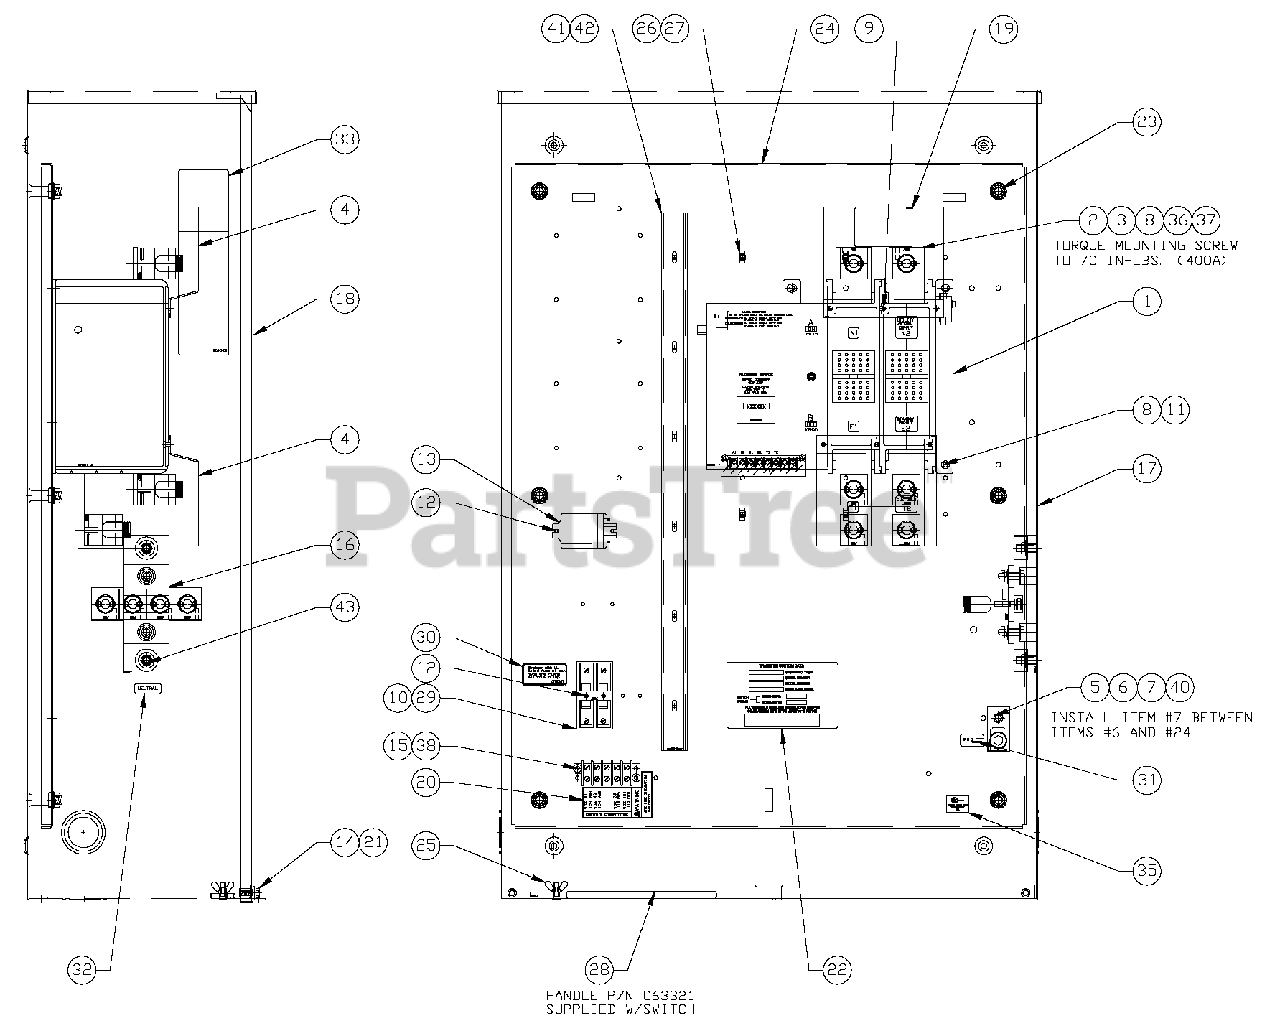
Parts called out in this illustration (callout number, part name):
1	XFER SW-W 400A600V2P
2	LUG SLDLSS 600/250-1/0X1/4-28
3	SCREW HHTT #8-32 X 1/4 CZ
4	COVER LUG 2P 300/400AMP
5	SCREW HHTT 5/16-18 X 3/4 CZ
6	LUG SLDLSS 350-#6 X 13/32 AL/CU
7	WASHER SHAKEPROOF EXT 5/16 STL
8	WASHER LOCK M6-1/4
9	SCREW PPHM DSEMS M4-7 X 10 ZNC
10	FUSEBLOCK 30A 600V 2 POS W/SQ
11	SCREW HHTT M6-1.0 X 12 ZINC
12	SCREW HHTT M4-0.7 X 10 BP
13	RELAY PNL 12VDC DPDT 10A@240VA
14	SCREW HHC M6-1.0 X 16 G8.8
15	RIVET POP .156 X .675 AL
16	ASSY TERMINAL BLOCK 300-400A
17	ENCL RTS 3R 24X36X10 08GRAY
18	COVER, NEMA 3R XFER SW 08GRAY
19	DECAL TERMINAL SHOCK HZD BI
20	DECAL TERMINAL STRIP
21	WASHER NYLON
22	DECAL,XFER SW NON 400A 120/240
23	NUT HEX FL WHIZ 3/8-16
24	SUBPLATE 24/36 ENCL RTS 08GRAY
25	NUT WING M6-1.0
26	HOLDER CABLE TIE
27	TIE WRAP UL 5.6 X .10 NATL
28	HANDLE XFER SWITCH 1-400A
29	FUSE 5A X BUSS
30	DECAL FUSE REPLACEMENT
31	DECAL GROUND LUG
32	DECAL NEUTRAL
33	DECAL MANUAL OPERATION
34	DECAL TEST SEQUENCE 3P TS 3R
35	DECAL-UL LIST HSB
36	SCREW HHC 1/4-28 X 5/8 .625TH
37	WASHER FLAT 1/4-M6 ZINC
38	BLOCK TERM 20A 5 X 6 X 1100V
39	DECAL SIEMENS 4.3" X 16.5"
40	WASHER LOCK M8-5/16
41	DUCT WIRING 1 X 1.5 (24" LG)
42	COVER WIRE DUCT 1 IN (24" LG)
43	NUT HEX FL WHIZ M8-1.25
